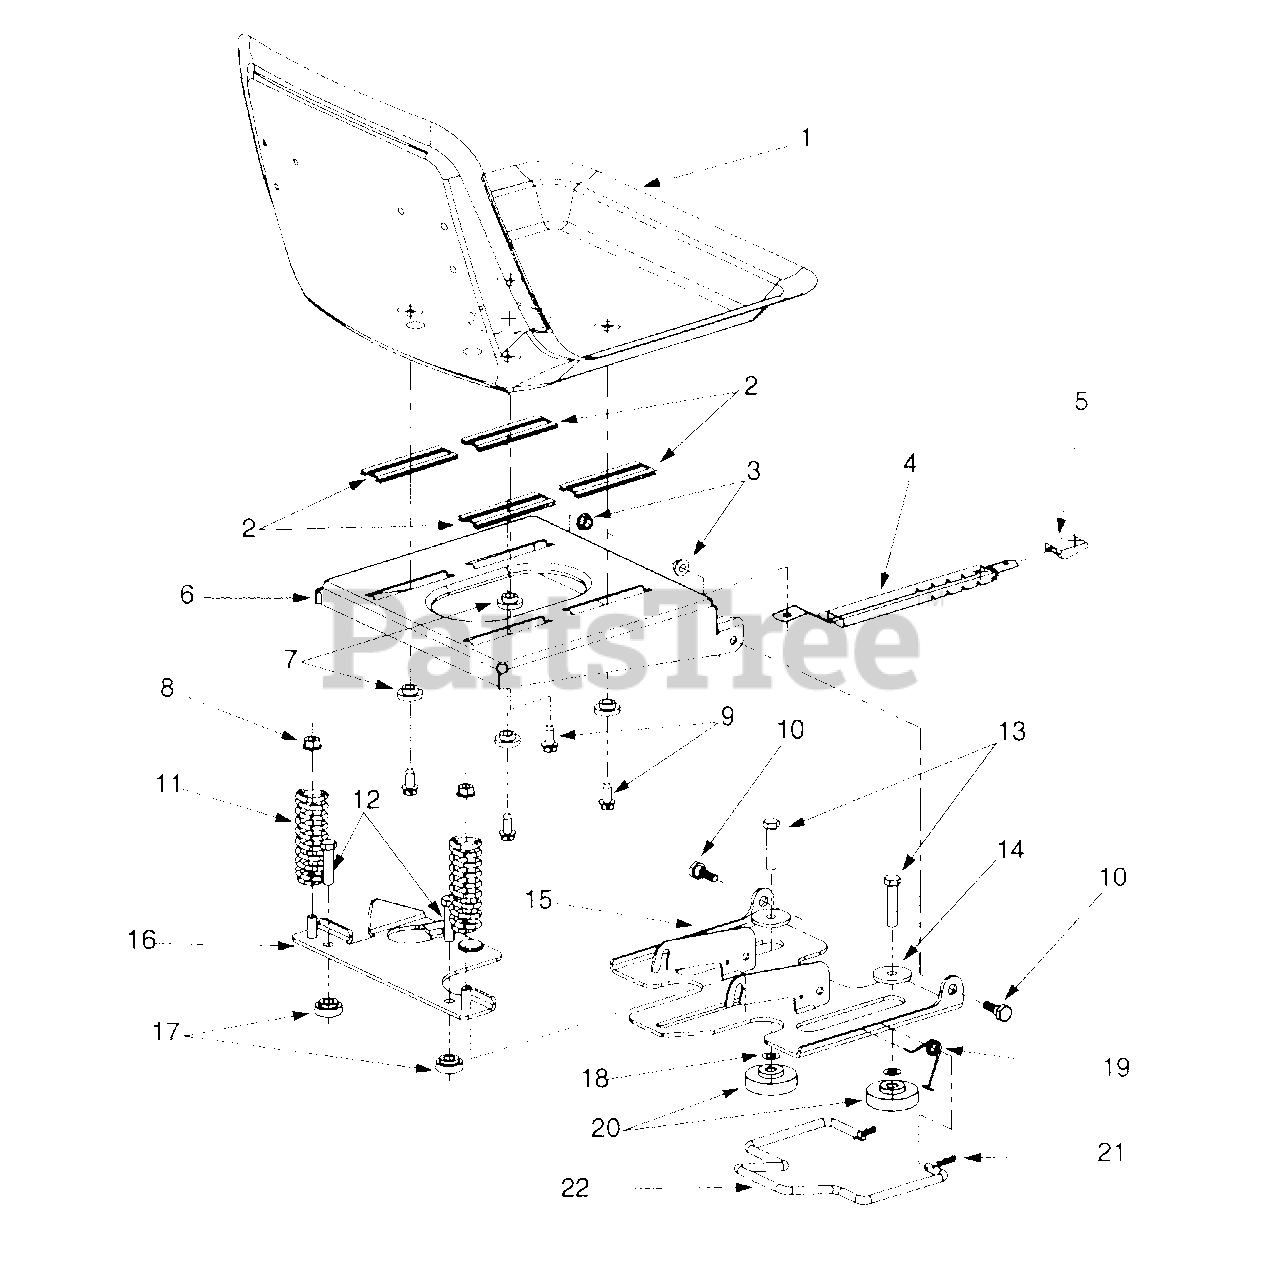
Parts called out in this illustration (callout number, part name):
1	Seat Assembly
2	Seat Slide
3	Flange Lock Nut 5/16-18
4	Spring Index
5	Knob
6	Bracket Assembly
7	Shoulder Spacer
8	Flange Lock Nut 3/8-16
9	Hex Washer Screw 5/16-18 x .75
10	Shoulder Screw
11	Compression Spring 1.28 OD x 3.5
12	Hex Cap Screw 3/8-16 x 1.5
13	Hex Cap Screw 3/8-16 x 1.75
14	Flatwasher
15	Seat Bracket Assembly
18	Thrust Washer
19	Torsion Spring
20	Shoulder Spacer
21	Cotter Pin
